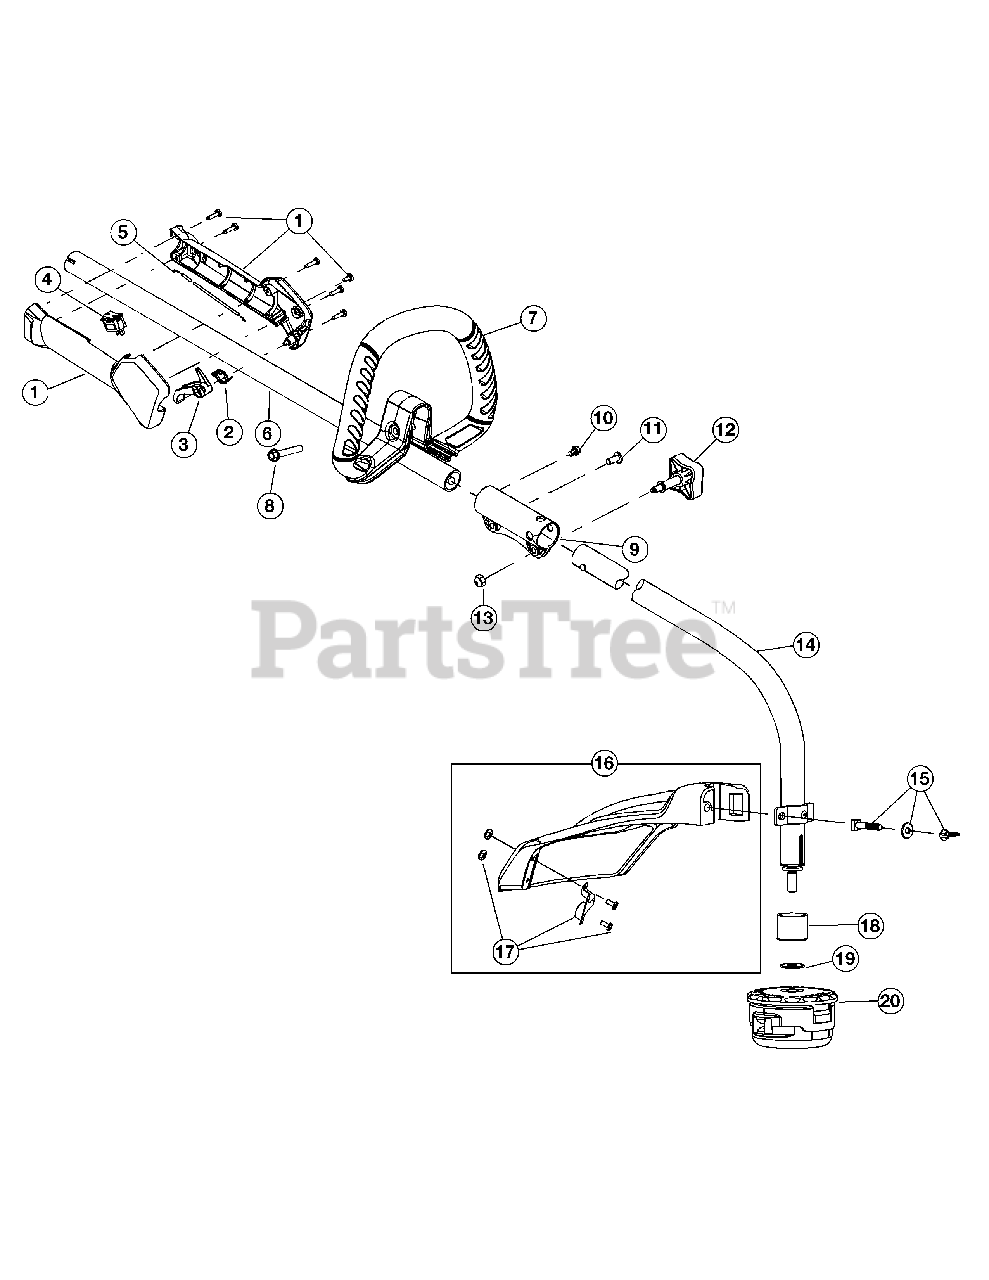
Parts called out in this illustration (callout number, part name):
1	Throttle Housing Assembly (Incl. 2 - 4)
2	Throttle Trigger Spring
3	Throttle Trigger
5	Throttle Cable Assembly
6	Upper Drive Shaft Housing Assembly
7	D-Handle Assembly (Incl. 8)
9	Split boom Coupler (Incl. 10 - 13)
12	Adjustment Knob (Incl. 13)
13	Knob Retaining Nut
14	Lower Drive Shaft Housing Assembly
15	Shield Mounting Hardware
16	Shield Assembly (Incl. 17)
17	Blade Assembly
19	Washer
20	Bump Head Assembly
